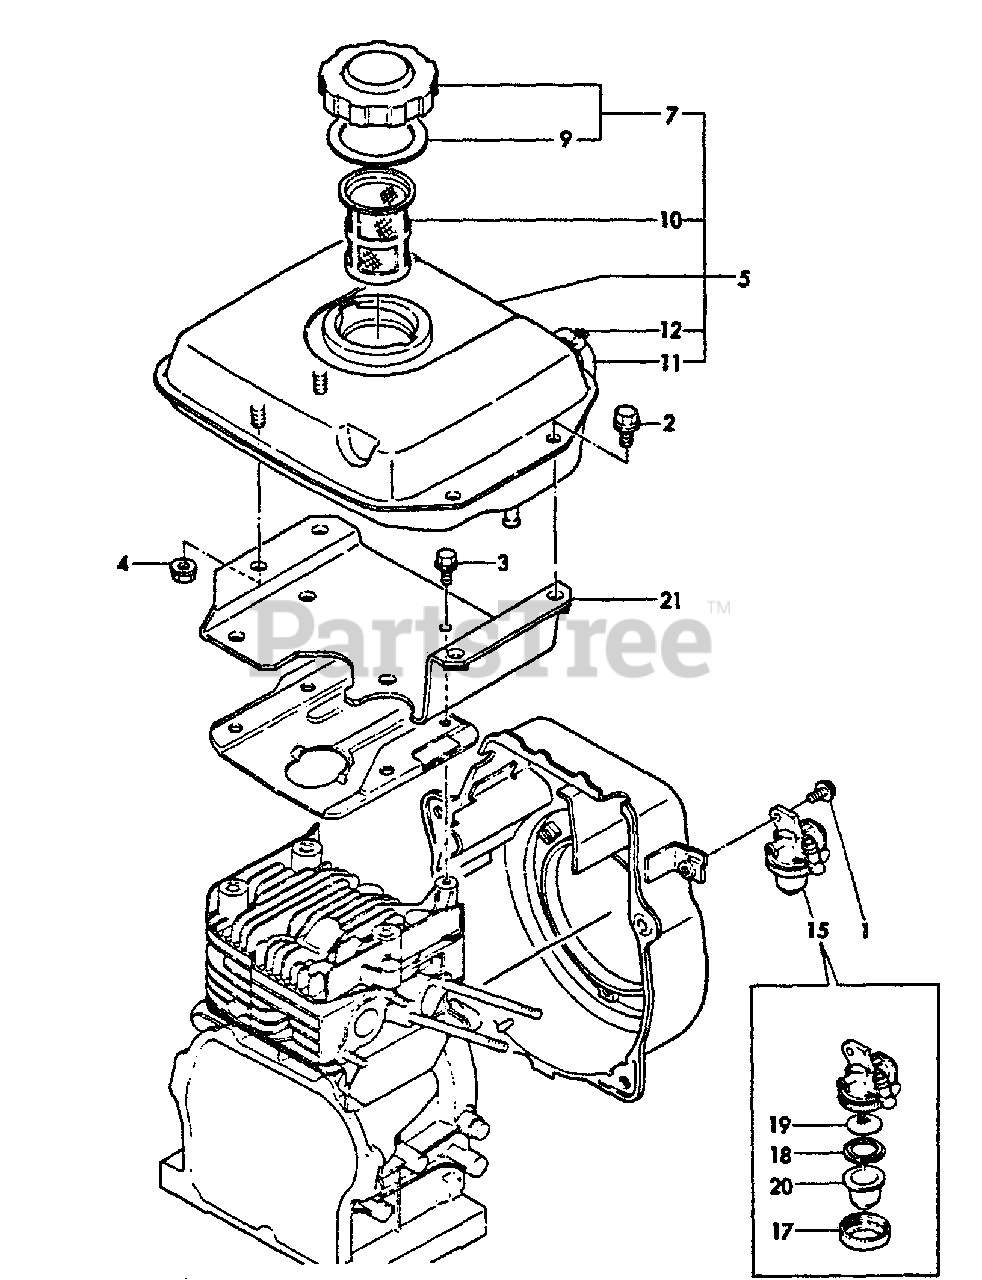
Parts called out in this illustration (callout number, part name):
1	BOLT - 6X12 -- PLATED
2	BOLT - 8X14 -- PLATED
3	BOLT - 6X8 -- PLATED
4	NUT - 8
5	FUEL TANK ASSY
7	CAP ASSY
9	GASKET
10	STRAINER, FUEL
11	GAUGE, LEVEL
12	CLAMP, HOSE - 9
15	FUEL COCK ASSY
17	RETAINER
18	GASKET
19	STRAINER, FUEL
20	BOWL, STRAINER
21	BRACKET, FUEL TANK
